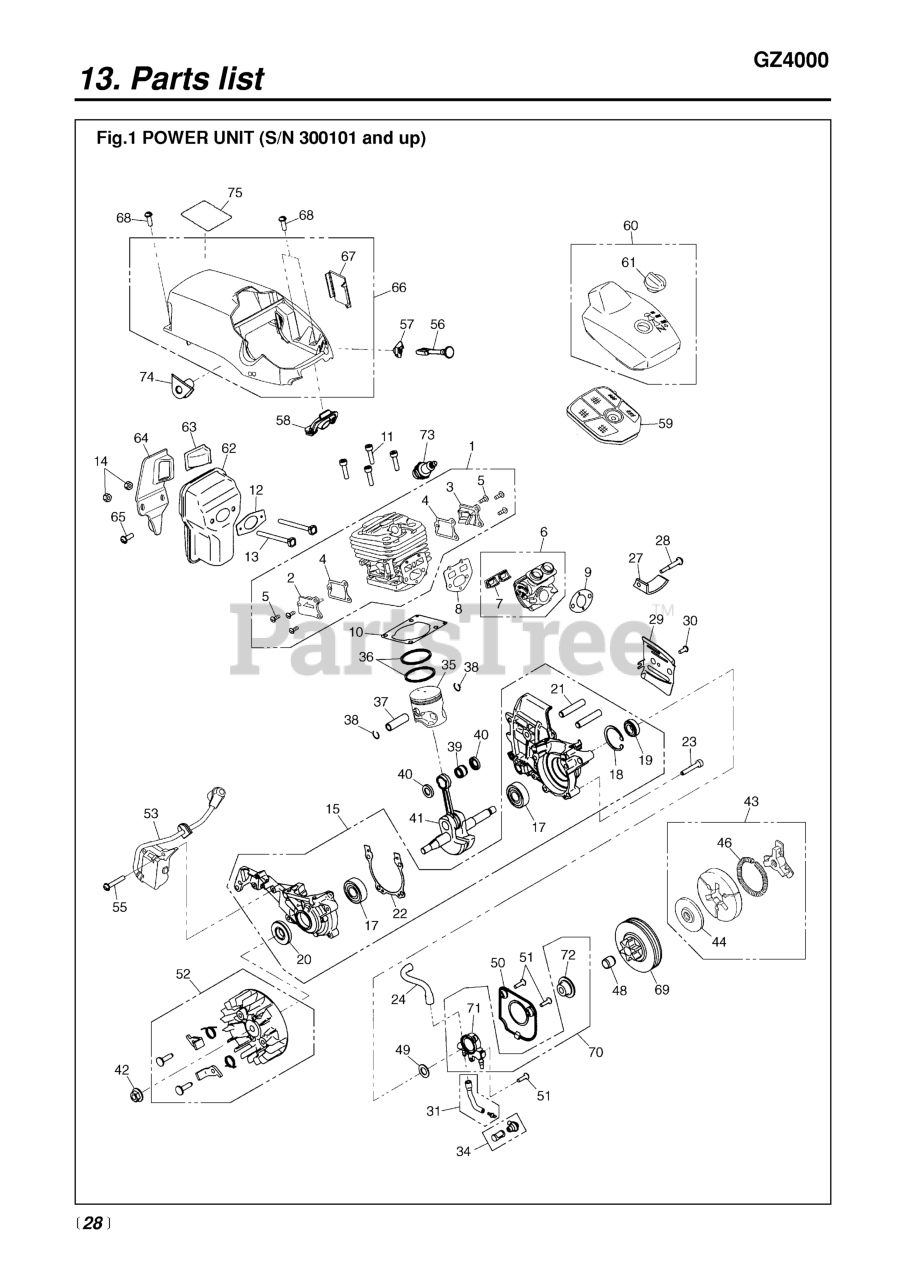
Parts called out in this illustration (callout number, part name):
1	CYLINDER ASSY
2	TR COVER MAG
3	TR COVER PTO
4	GASKET
6	INSULATOR ASSY
7	SEAL
8	GASKET
9	GASKET
10	GASKET, CYLINDER
11	BOLT (RPLS 2850-14220)
12	GASKET, MUFFLER
13	BOLT, MUFFLER
14	NUT, MUFFLER (RPLS 3356-15230
15	CASE ASSY
17	BEARING
18	RING, SNAP, M32 x 1.2
19	SEAL, OIL (RPLS 1100-21210)
20	SEAL
21	STUD (RPLS 0205-50825)
22	GASKET, CASE
23	BOLT
24	PIPE
27	CATCHER, CHAIN (RPLS -25210)
29	PLATE (A)
31	PIPE
34	FILTER COMPLETE
35	PISTON
36	RING
37	PIN
38	RING, SNAP
39	BEARING
40	WASHER
41	SHAFT COMP
44	PLATE
46	SPRING
48	BEARING
49	WASHER
50	COVER, PUMP
51	SCREW
52	ROTOR COMP
53	COIL ASSY
55	SCREW
56	ROD, CHOKE
57	GROMMET, CHOKE
58	GROMMET, THROTTLE
59	CLEANER ASSY
60	COVER COMP
61	KNOB (RPLS 3356-83322)
62	MUFFLER
63	ARRESTER, SPARK
64	STAY
65	SCREW (REPLACES 2616-24320)
66	COVER COMP
68	SCREW
69	DRUM, CLUTCH
71	PUMP, OIL (USE 848-C40-67A1)
72	WORM GEAR
73	PLUG, SPARK (RZ7C)
74	GROMMET
75	LABEL
NI	PIN
NI	PIPE
NI	PIPE IN
NI	SHOE
NI	BOSS
